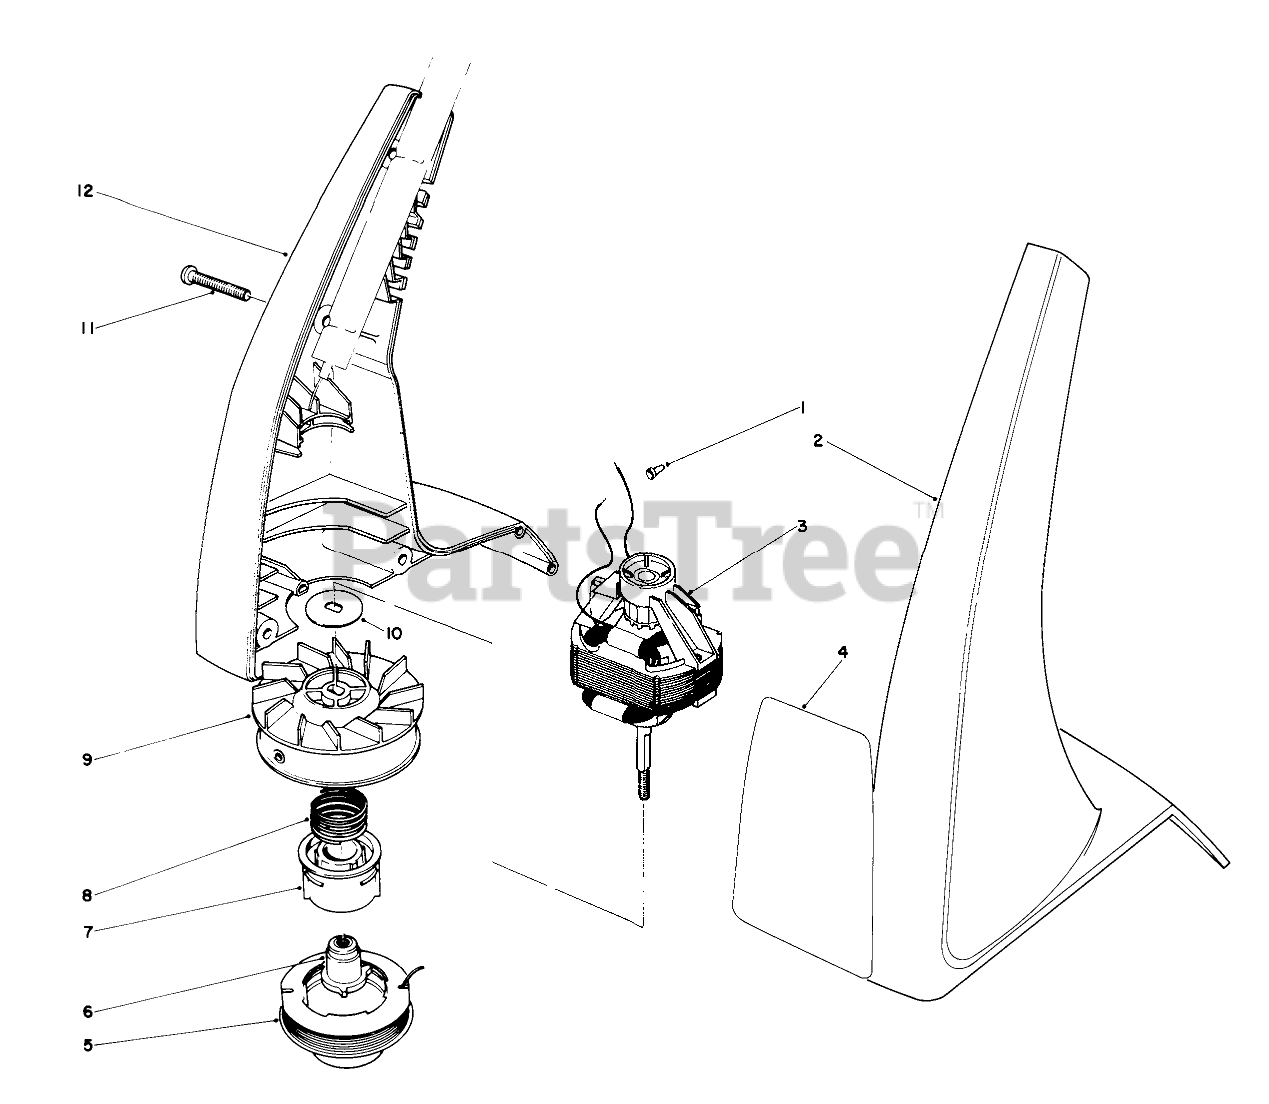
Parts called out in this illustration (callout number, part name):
1	CONNECTOR WIRE JOINT
2	L.H. HOUSING, 910
3	MOTOR, 910 TRIMMER
4	910 DECAL
5	Prewound Spool
6	DRIVER
7	CORE - SPOOL
8	Spring
9	Drum w/Eyelet
10	MOTOR WASHER
11	Screw
12	Housing-R.H.
